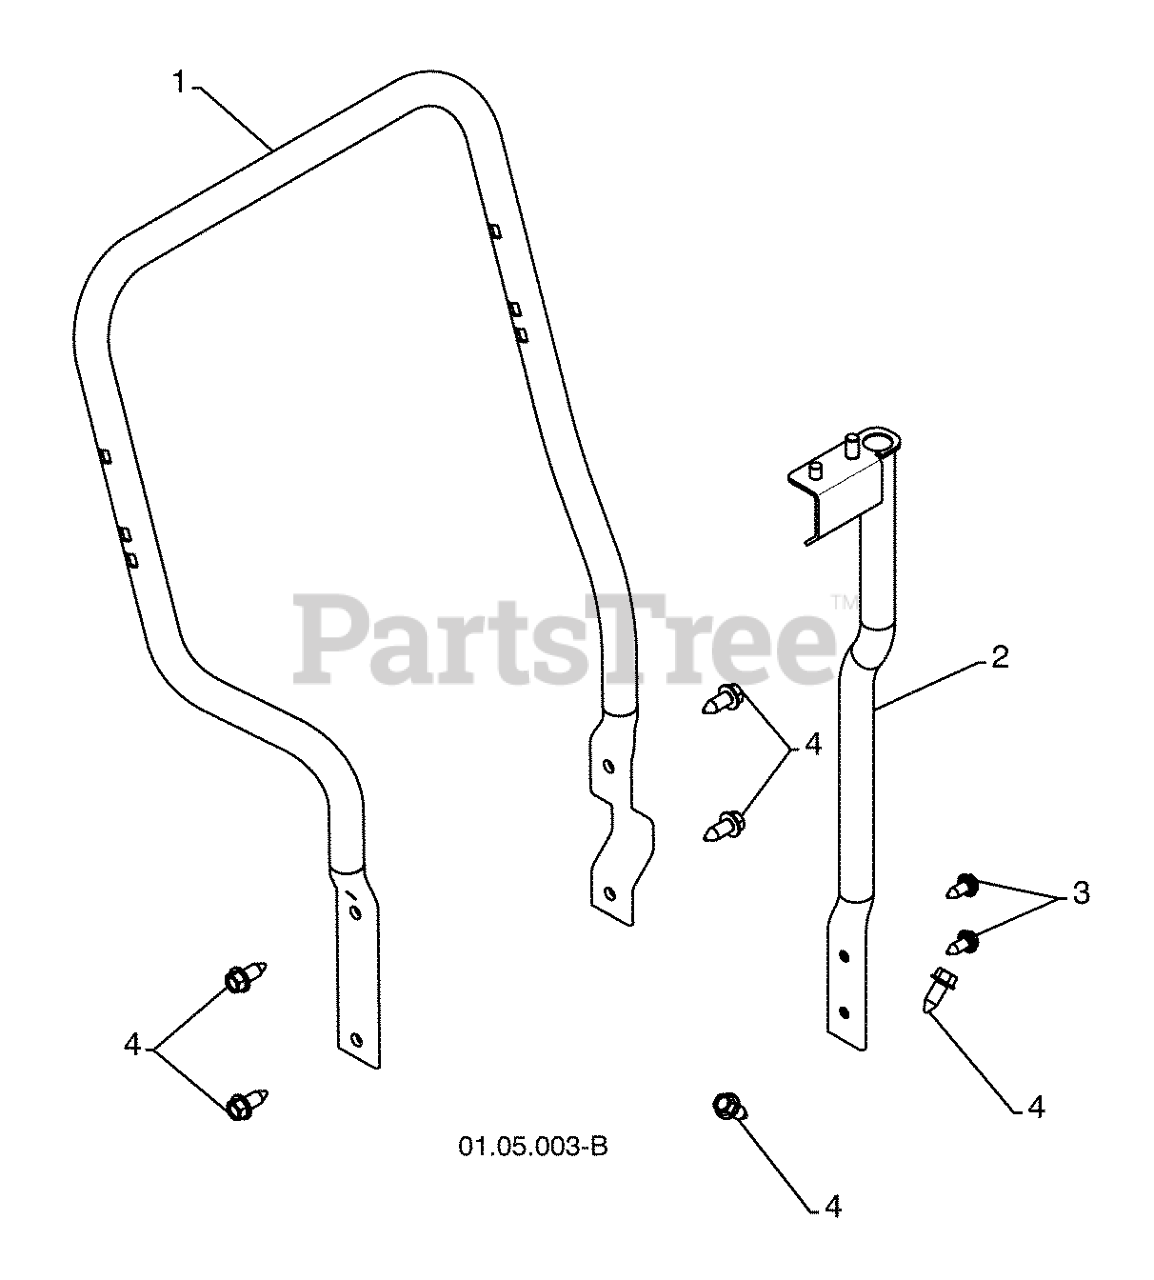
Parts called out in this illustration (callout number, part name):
1	TUBE.LOWER.HANDLE.SNOW.BLACK
2	SUPPORT.WELDMENT.ROTATOR.
3	SELF-TAPPING SCREW 5/16-18X3/4
4	SCREW 3/8-16X1
